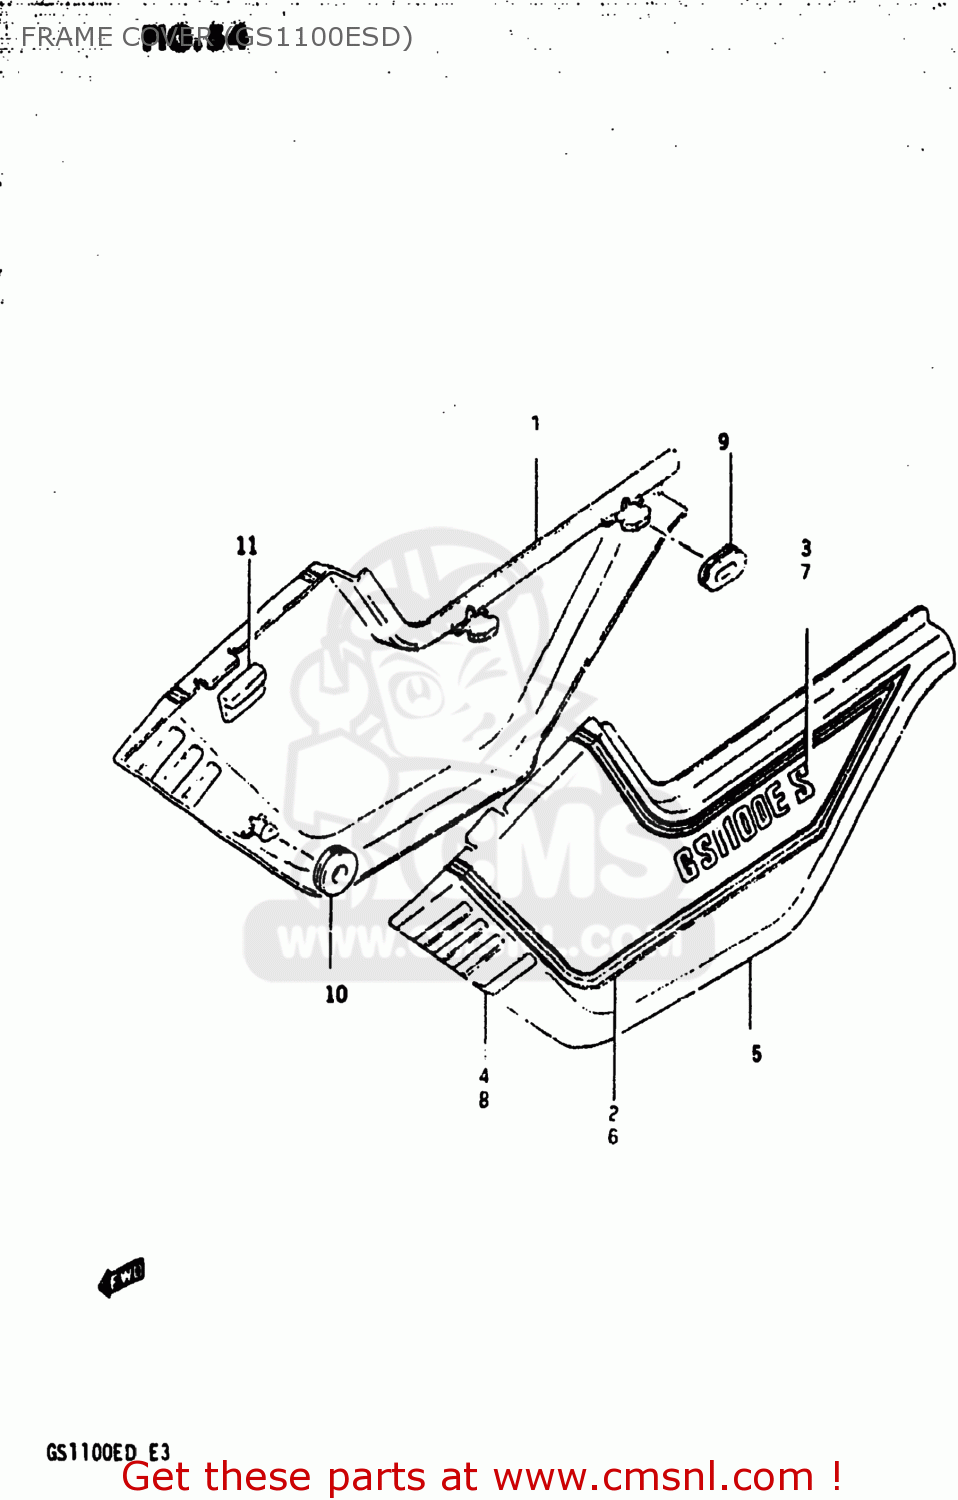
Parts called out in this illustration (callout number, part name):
1	COVER,FRAME,RIGHT
2	TAPE SET,FRAME COVER,RIGHT
3	EMBLEM,FRAME COVER
4	LABEL, DENT
5	COVER,FRAME,LEFT
6	TAPE SET,FRAME COVER
7	EMBLEM,FRAME COVER
8	EMBLEM,FRAME COVER,CENTER
9	CUSHION
10	CUSHION
11	CUSHION,FRAME COVER
